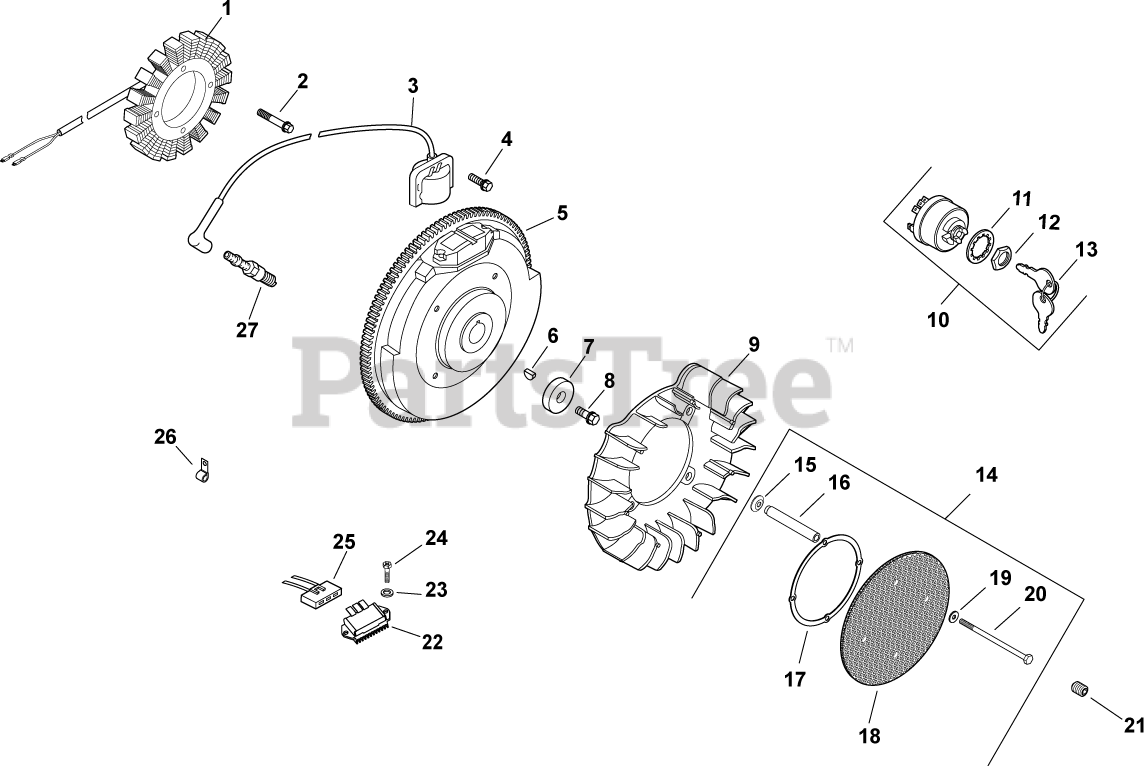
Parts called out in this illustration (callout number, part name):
1	KIT, 15 / 20 AMP STATOR
2	SCREW, M5X0.8X25 - (#25086402S)
3	KIT, MODULE IGNTN (CDI FIXED)
4	SCREW, FLG THD FRM M5X.8X20-(#25086399S)
5	FLYWHEEL, PAINTED-USE 24 025 59-S
6	KEY, 3/16" X 5/8"
7	WASHER, FLAT 13/32"
8	SCREW, FLG M10X1.5X45 - (#25086361S)
9	FAN USE 24 755 253-S
10	SWITCH ASSY, KEY (KM)-USE 25 099 32-S
11	WASHER, INTERNAL TOOTH
12	NUT, KEY SWITCH
13	KEY, SET -USE 48 340 01-S
14	KIT, CHOPPER SCREEN
15	WASHER, SPRING 10 MM
17	RING, SUPPORT USE 25 141 08-S
18	SCREEN, GRASS
19	WASHER, FLAT 1/4" (O.D. 5/8")
20	SCREW, CAP M6X1.0X99.5
21	SCREW, SKT SET #10-24X1/4"
22	REG/RECT-15 AMP (KM)-USE 41 403 10-S
23	WASHER, FLAT 1/4" (O.D. 1/2")
24	SCREW, PHL HD #11-16X7/8"
25	CONNECTOR, BODY (KM)-USE 25 155 41-S
26	CLIP, CABLE
27	PLUG, SPARK (STD)
